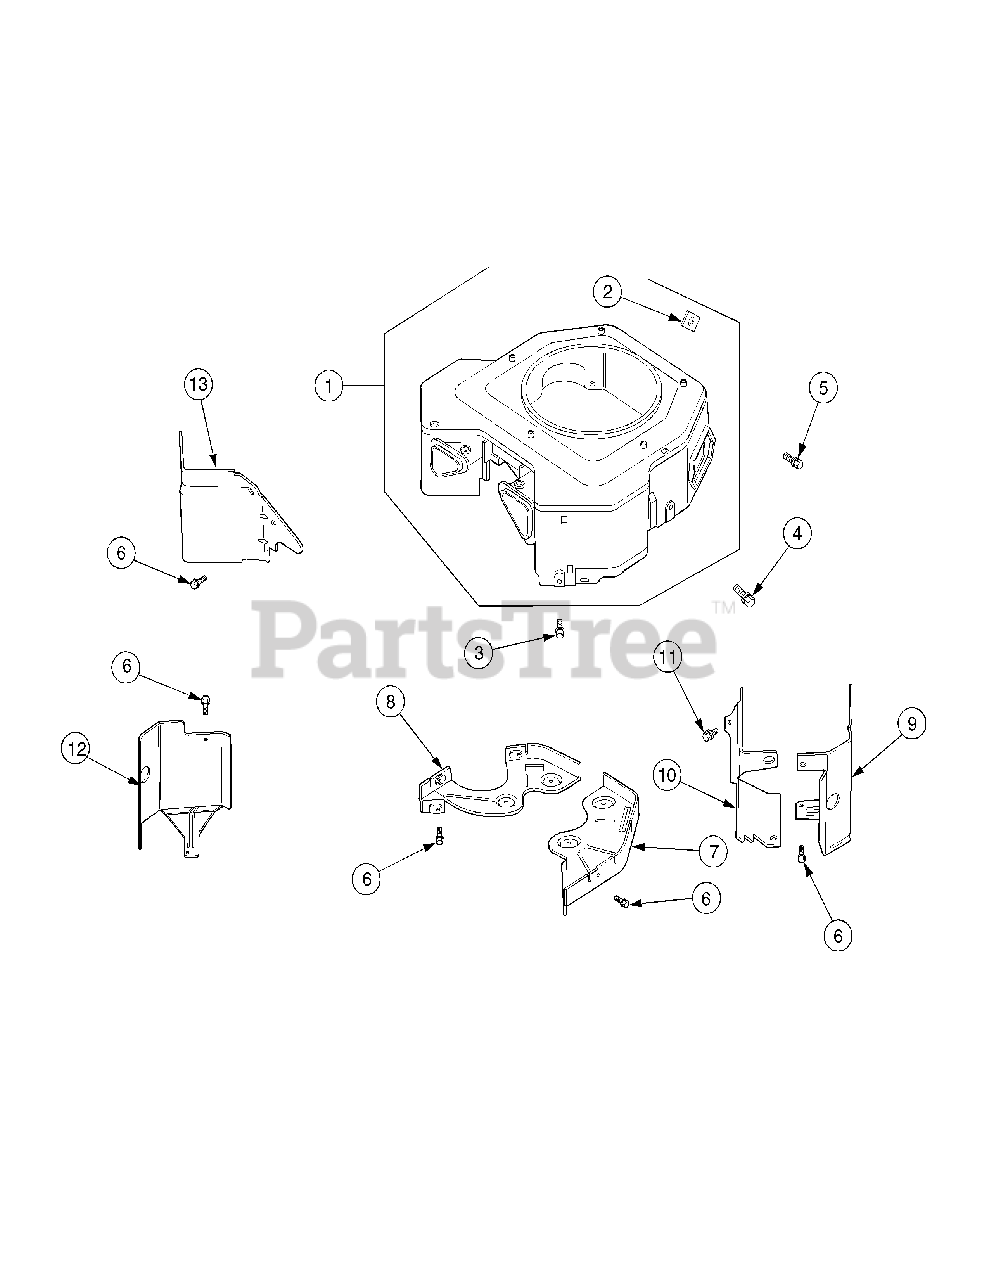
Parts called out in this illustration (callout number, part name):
1	Housing, Blower
2	Nut, Plastic
3	Screw, Hx Flange, M5-0.8 x 20
4	Screw, Hx Flange, M5-0.8 x 16
5	Screw, Hx Flange, M5-0.8 x 16
6	Screw, Hx Flange, M6-1.0 x 16
7	Plate, Backing, #2 Side
8	Plate, Backing, #1 Side
9	Baffle, Cylinder Barrel, #2 Side
10	Baffle, Valley, #2 Side
11	Screw, Hx Flange, M5-0.8 x 10
12	Baffle, Cylinder Barrel, #1 Side
13	Baffle Valley, #1 Side
